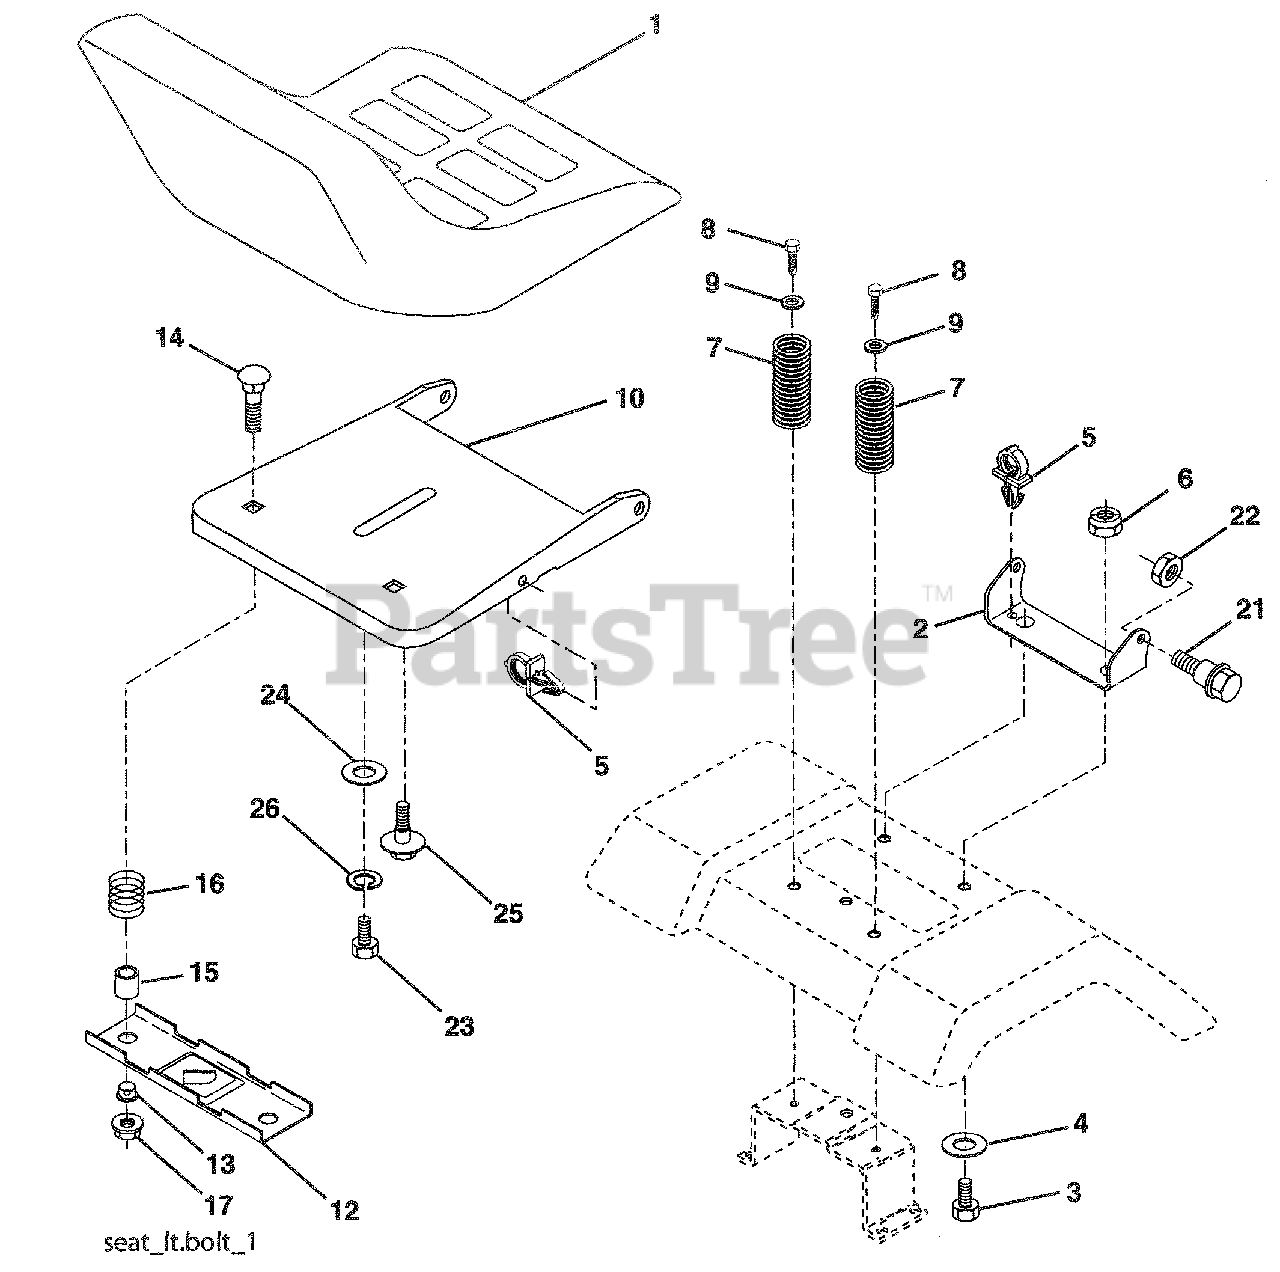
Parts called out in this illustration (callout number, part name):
1	Seat
2	Bracket Seat Pivot
3	Bolt Hex 3/8 - 16 x 1
4	Washer 13/32 x 1 x 10 Ga.
5	Clip Push-In Hinged
6	Nut Lock Hex w/lns 3/8-16
7	Spring Seat Cprsn 2 250 Blk Zi
8	Screw 3/8-16 x 1.5
9	Washer 13/32 x 1 x 14 Ga.
10	Pan Pnt Seat (Blk)
12	Bracket Pnt Mounting Switch
13	Bushing Snap Blk Nyl
14	Bolt Rdhd Sht Nk 1/4 - 20 x 1 -1/2
15	Spacer Split .28 x .96
16	Spring Cprsn
17	Nut Lock 1/4 Lge Flg
21	Bolt Shoulder 5/16-18 unc-2A
22	Nut Lock Hex w/lns 5/16 - 18
23	Bolt Hex
24	Washer 17/32 x 1-3/16 x 12 Ga.
25	Bolt Shoulder 5/16-18 x .62
26	Washer Lock Hvy Hlcl Spr 1/2
